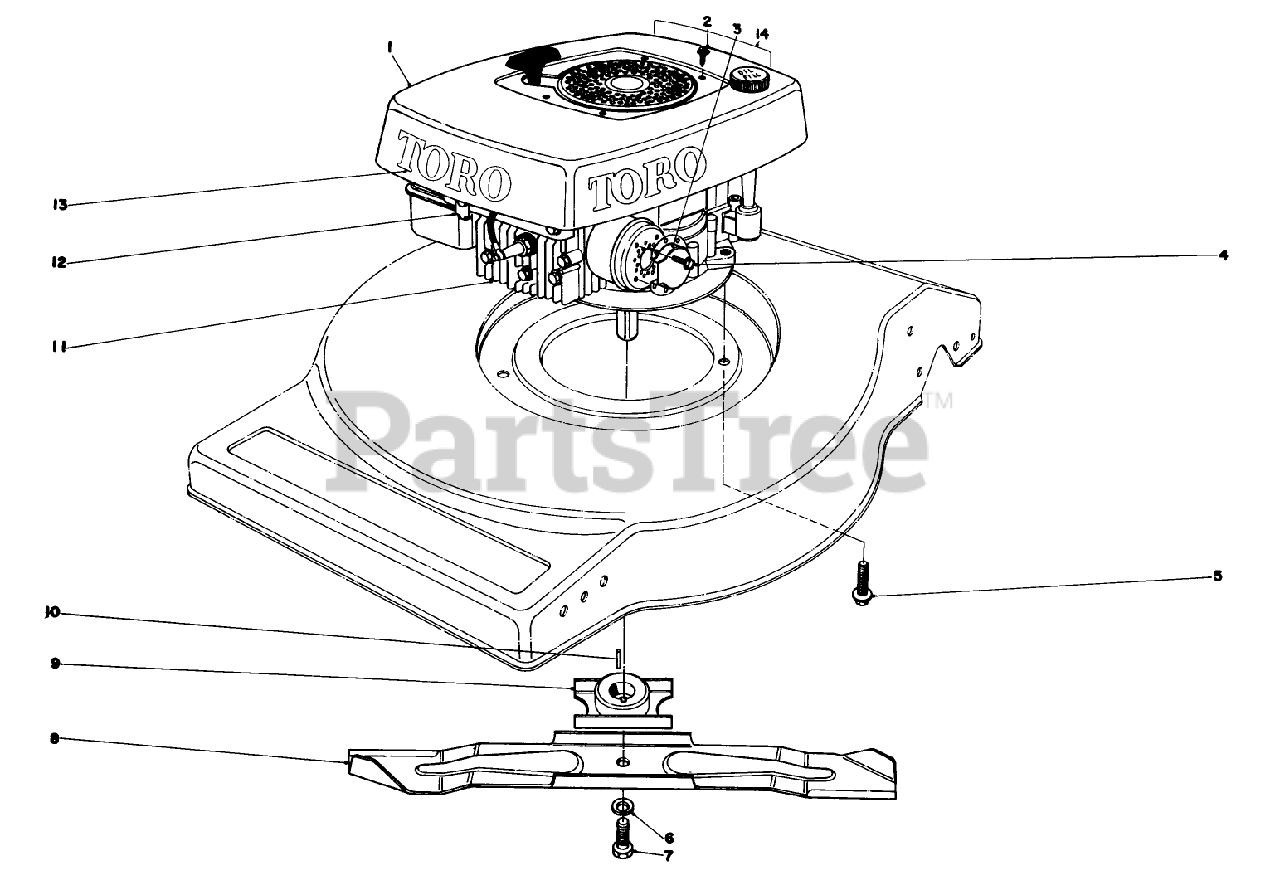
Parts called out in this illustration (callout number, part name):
1	Shroud
2	SCREW-THD FORM, HWH
3	Deflector
4	SCREW W/ENGINE
5	SCREW-HWHTF
6	WASHER-LOCK
7	SPECIAL SCREW
8	Blade
9	Blade Retailer
10	KEY-SQUARE
11	Engine
12	Bracket Control
13	Decal-TORO
14	Decal-Maintenance
